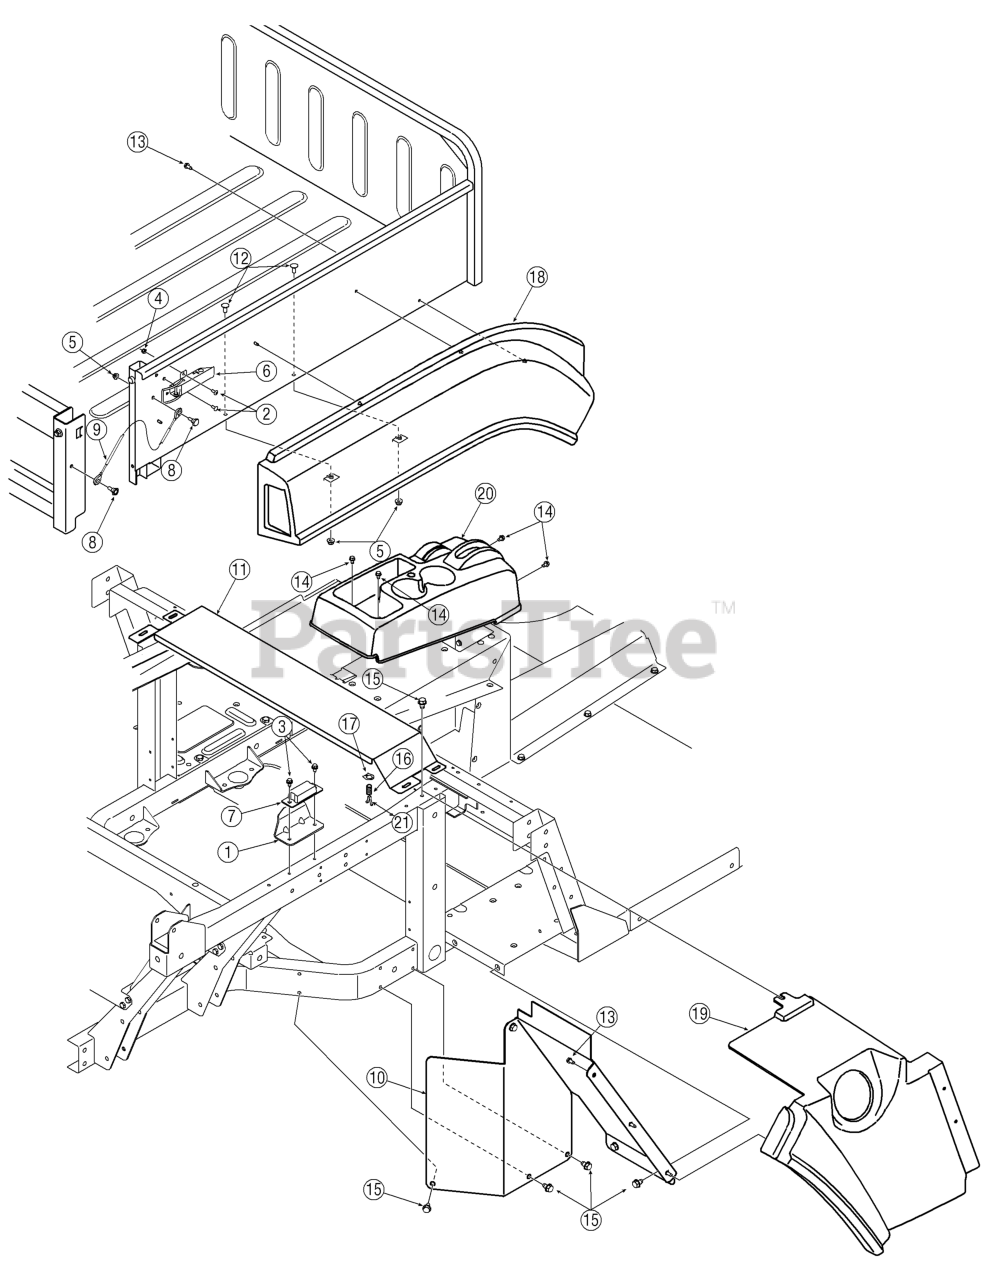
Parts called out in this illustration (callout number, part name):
2	Scr, mach, #10-24, 0.500, trusphi
3	Scr, tt, 1/4-20x.625, hxindwsh, ca
4	Nut, hexlk, #10-24, gr2, nylon
5	Nut, flglk, 1/4-20, grf, nylon
6	Latch, draw, over Center
7	Bmpr, suspn, extn
8	Scr, shldr, .375x.280, 1/4-20
9	Cbl, lanyard
12	Scr, Crg, 1/4-20, .62, Gr2 (not on camo units)
13	Scr, #12-16, .50, Hxindwsh
14	Scr, Tt, 1/4-20, 0.500
15	Scr, Tt, 5/16-18, 0.500
16	Spr, Comprs, .40 OD X .
17	Latch, Pnl, 1/4 Turn
18	Fdr, Rh Rr
18	Fdr, Rh Rr, Camo
19	Fdr, Lwr Rh Rr
19	Fdr, Lwr Rh Rr Camo
20	Cnsol, Seat
21	Spr, Clip
